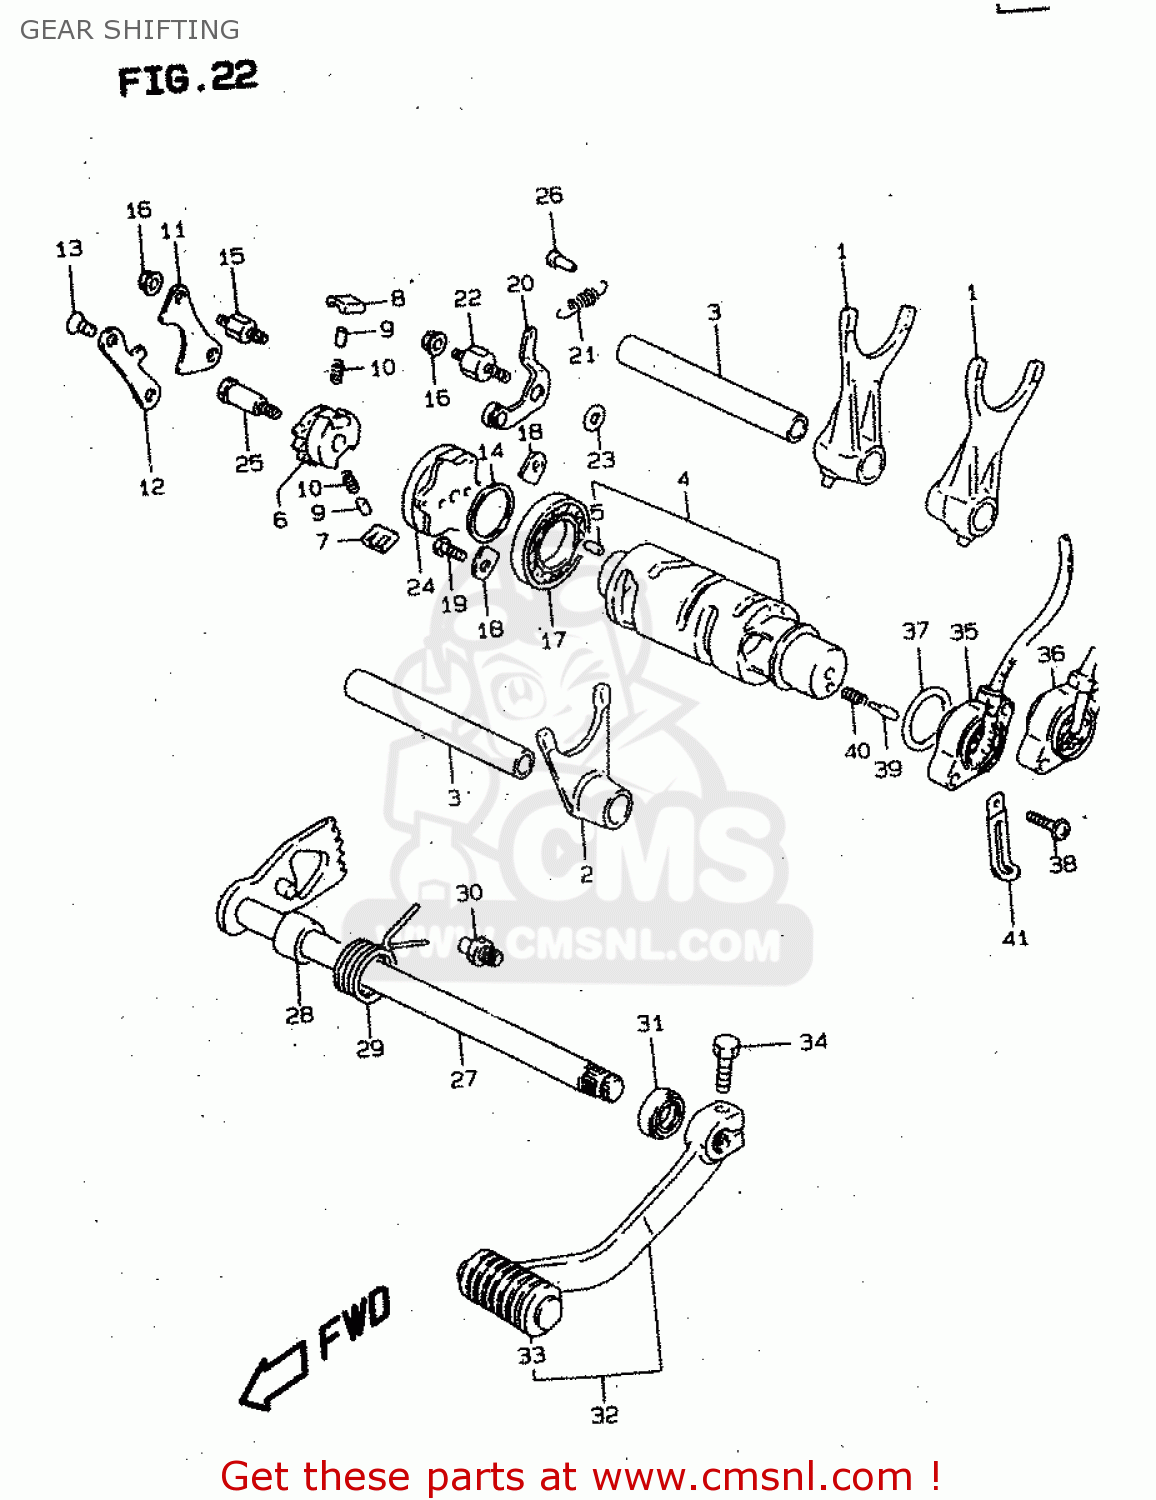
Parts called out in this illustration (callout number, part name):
1	FORK,GEAR SHIFT NO.1
2	FORK,GEAR SHIFT NO.2
3	SHAFT,GEAR SHIFT FORK(L:115)
4	CAM,GEAR SHIFT
5	PIN
6	GEAR,GEAR SHIFT CAM DRIVEN
7	PAWL,GEAR SHIFT NO.1
8	PAWL,GEAR SHIFT NO.2
9	PIN(5X8)
10	SPRING
11	LIFTER,GEAR SHIFT POLE
12	GUIDE,GEAR SHIFT CAM
13	SCREW
14	WASHER(25X32X3)
15	BOSS,SHIFT PAWL LIFTER
16	NUT
17	BEARING(25X47X8)
18	RETAINER
19	SCREW
20	STOPPER,GEAR SHIFT CAM
21	SPRING
22	SUPPORT,CAM STOPPER ARM
23	WASHER
24	PLATE,GEAR SHIFT CAM
25	PIN,SHIFT CAM DRIVEN GEAR
26	RIVET
27	SHAFT,GEAR SHIFT
28	SPACER(12X20X15.3)
29	SPRING
30	STOPPER,GEAR SHIFT CAM
31	OIL SEAL
32	LEVER ASSY,GEAR SHIFT
33	RUBBER,GEAR SHIFT PEDAL
34	BOLT
35	BASE,NEUTRAL SWH TERMINAL
36	BASE ASSY,GEAR SHIFT TERMINAL
37	O RING(D:2.4,ID:25.7)
38	SCREW
39	PIN(5X15.5)
40	SPRING
41	CLAMP(L:65)
